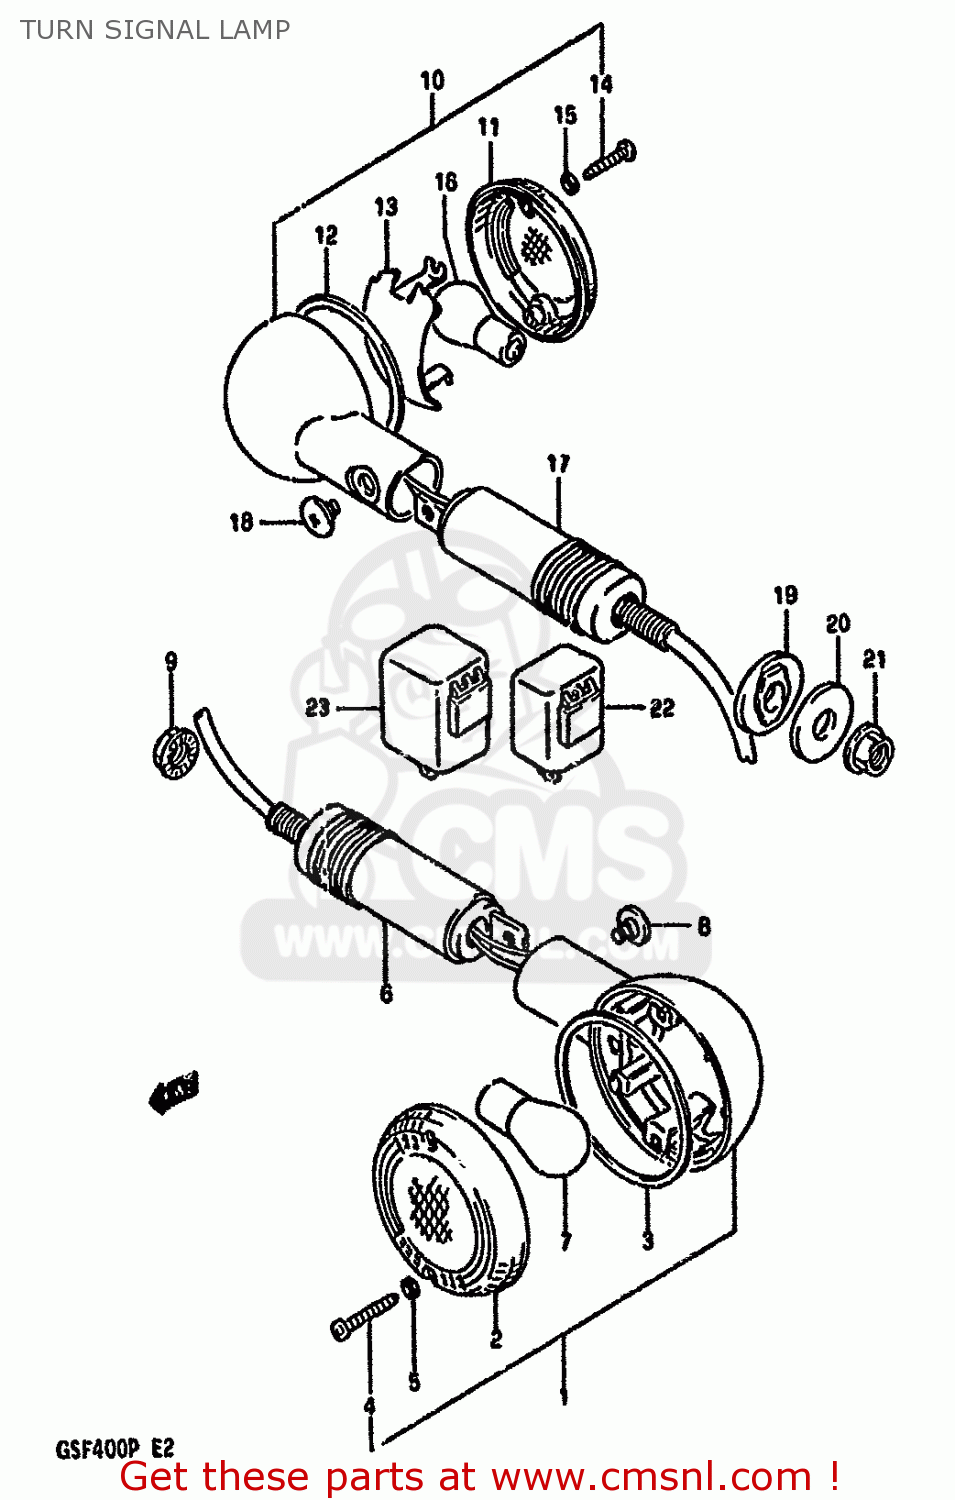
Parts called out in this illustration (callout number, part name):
1	LAMP ASSEMBLY,FRONT TURN SIGNAL
2	LENS
3	GASKET (NAS)
4	SCREW ,4X25
5	GASKET (NAS)
6	STAY,TURNSIGNAL FR
7	BULB(12V21W)
8	SCREW
9	NUT
10	LAMP ASSY,REAR TURN RH
11	LENS
12	GASKET (NAS)
13	REFLECTOR
14	SCREW ,4X25
15	GASKET (NAS)
16	BULB(12V21W)
17	STAY,TURNSIGNAL RR
18	SCREW
19	SPACER,RR TURNSIGNAL
20	WASHER(10.5X30X3.2)
21	NUT
22	RELAY ASSEMBLY,TURN SIGNAL
23	RELAY ASSY,TUR
